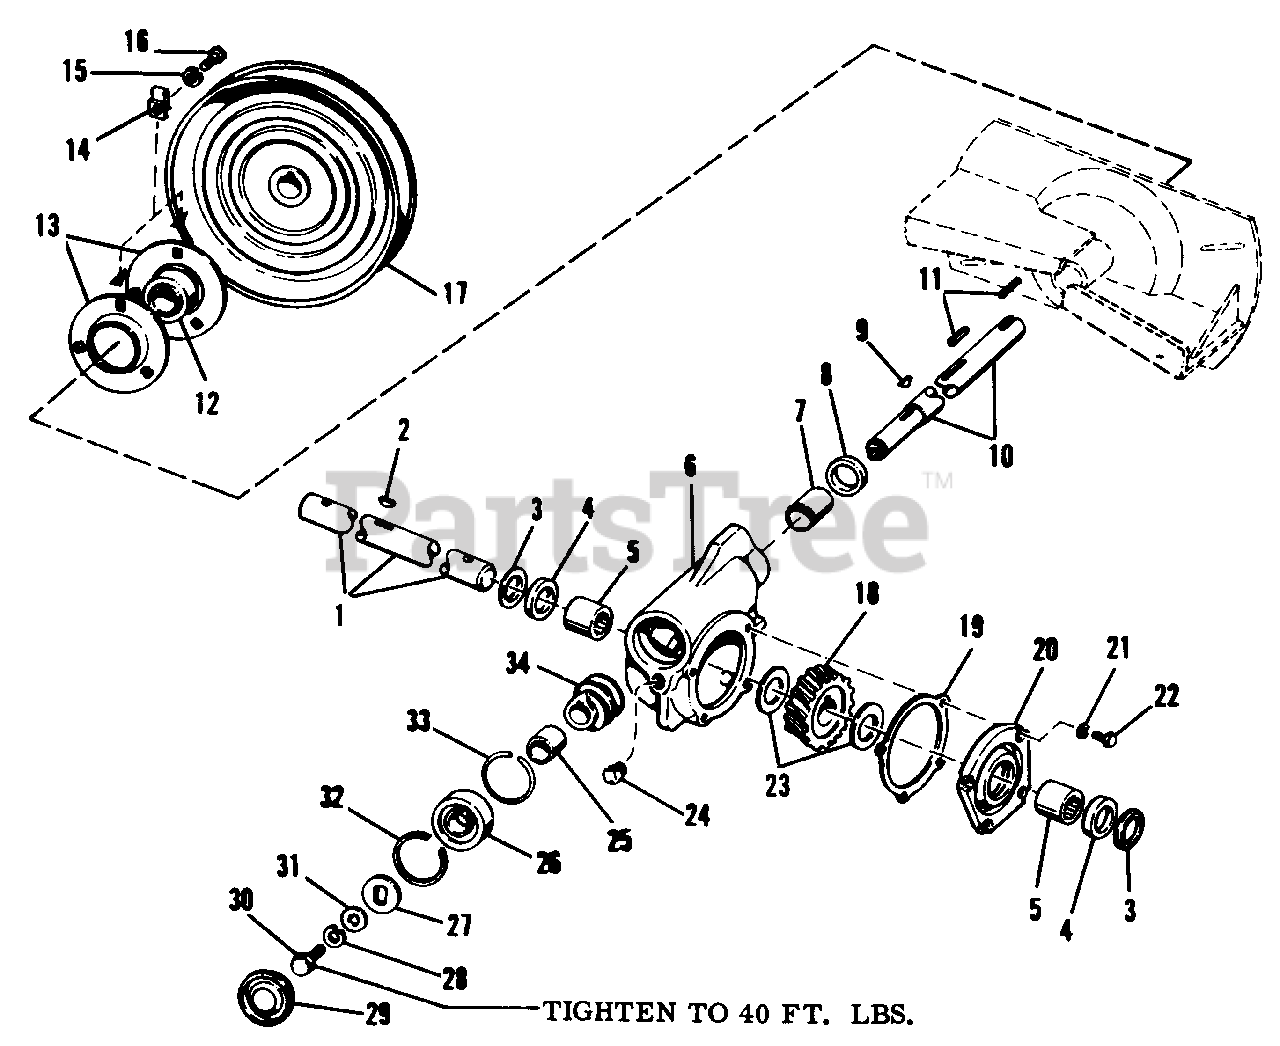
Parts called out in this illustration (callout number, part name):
1	SHAFT-worm gear
2	KEY-woodruff
3	WASHER
4	SEAL-oil
5	BEARING-needle
6	HOUSING-worm drive
7	BUSHING
8	SEAL-oil
9	KEY-3/16 x 7/8
10	SHAFT-worm gear
12	BEARING-cartridge
13	BEARING-flange
14	NUT-retainer
15	WASHER-lock, 5/16
16	SCREW-hex cap, 5/16
17	PULLEY
18	GEAR-worm
19	GASKET
21	WASHER-lock, 1/4"
22	SCREW-hex, cap, 1/4-20x 5/8
23	WASHER-thrust
24	PLUG-pipe, 3/8"
26	BEARING-ball
28	WASHER-lock, 3/8"
30	SCREW-hex cap, 3/8-24 x 1
31	WASHER-flat, 5/16
32	RING- retaining
33	RING-snap
